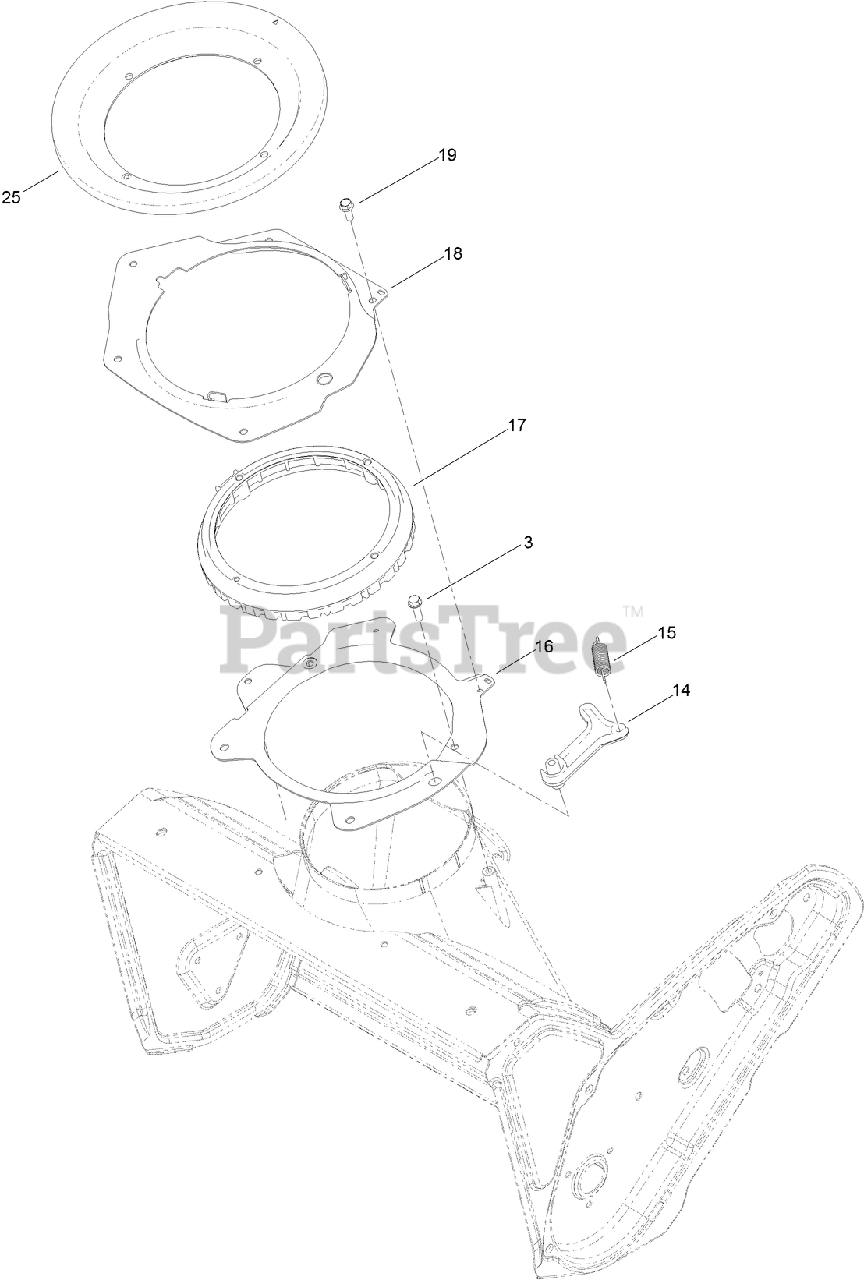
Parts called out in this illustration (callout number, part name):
3	SCREW-HWH
14	PAWL-DETENT
15	SPRING-EXTENSION
16	RING-SUPPORT, CHUTE
17	RING-CHUTE, DETENT
18	RETAINER-RING, CHUTE
19	SCREW-HWH
25	SEAL-RING, CHUTE
